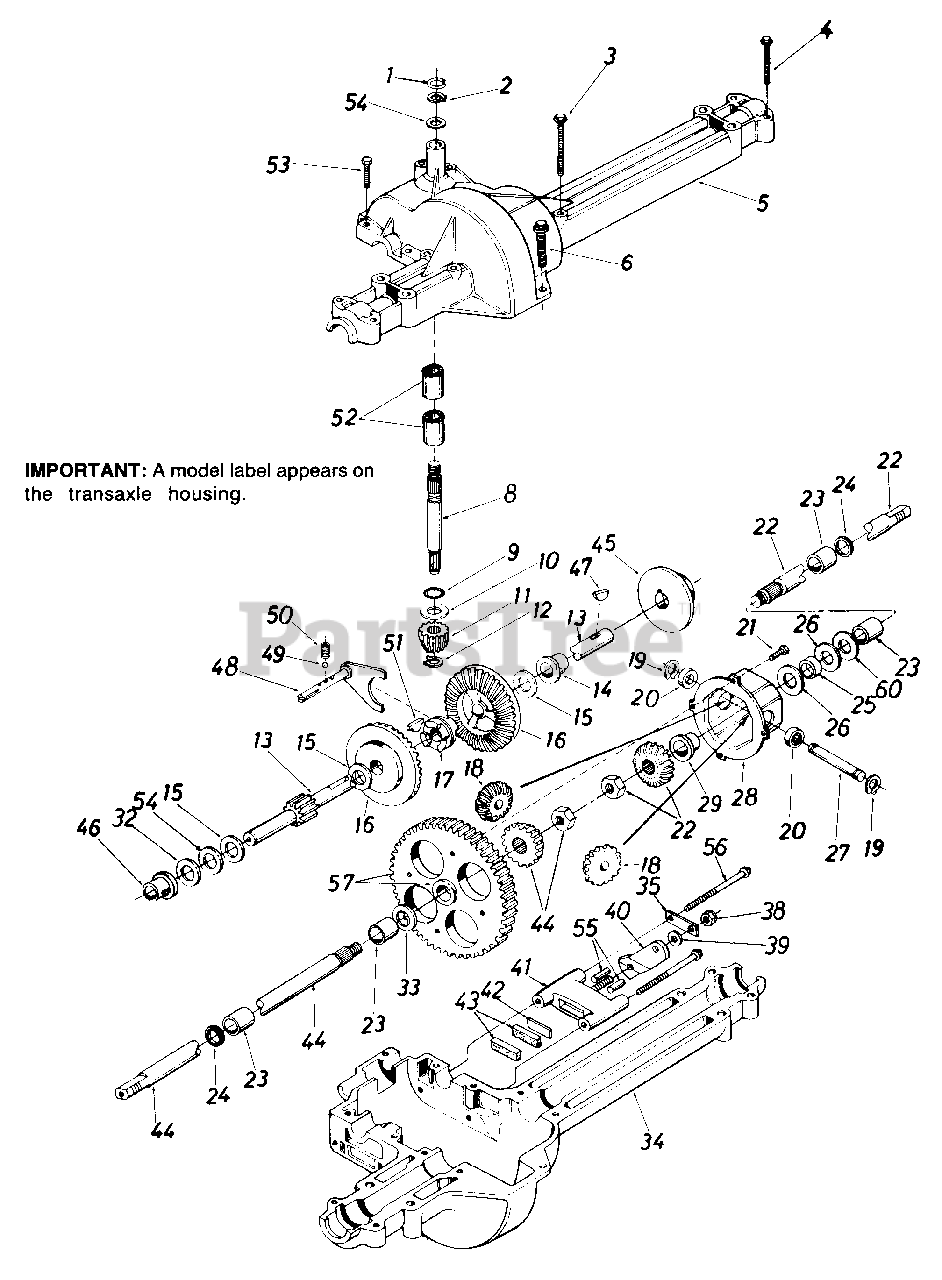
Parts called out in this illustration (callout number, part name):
1	Wire Ring
2	Retaining Ring
3	Hex Bolt 1/4-20 x 1.75" Lg.
4	Hex Tap Scr. 1/4-20 x 1.25" Lg.
5	Upper Housing
6	Hex TT-Tap Scr. 1/4-20 x .75" Lg.
8	Input Shaft
9	Square Seal 5/8" I.D.
10	Thrust Washer 5/8" I.D. x 1 25" O.D.
11	Pinion Input 14T
12	Retaining Ring
13	Drive Shaft
14	Flange Brg. 5/8" I.D. x 3/4" Lg.
15	Fl-Wash. 5/8" I.D. x 1.25
16	Bevel Gear 42T
17	Clutch Collar
18	Miter Gear 15T (H.D.)
19	Snap Ring
20	Thrust Bearing
21	Pan Head Scr. 1/4-20 x .50" Lg. w/Patch
22	Axle R.H. Ass'y.
23	Sleeve Bearing 3/4" I.D. x 1.0" Lg.
24	Oil Seal 3/4" I.D.
25	Axle Spacer
26	Fl-Wash. .760" I.D. x 1.5" O.D.
27	Cross Shaft
28	Differential Cam Ass'y.
32	Washer
33	Fl-Wash. .760" I.D. x 1.5" O.D.
34	Lower Housing
35	Anti-Rotation Brkt.
38	Hex Nut 5/16-24 Thd.
39	Fl-Wash. .344" I.D. x .875" O.D.
40	Actuating Arm
41	Brake Yoke
42	Puck Plate
43	Brake Puck
44	Axle L.H. Ass'y.
45	Brake Disc
46	Flange Bearing 5/8" I.D. x 15/16" Lg.
47	Woodruff Key 3/16 x 5/8 HT
48	Shift Fork Ass'y.
49	Ball Detent .250" Dia.
50	Spring Detent
51	#9 Hi-Pro Key 3/16" x 3/4" Dia. HT
52	Needle Brg. 5/8" I.D. x 1/2" Lg.
53	Hex Bolt 1/4-20 x 1.00" Lg.
54	Fl-Wash. 5/8" I.D. x 1" O.D. x .020 Thk.
55	Actuating Pin 5/16" Dia.
56	Hex Wash Hd. Self-Tap Scr. 1/4-20 Thd.
57	Differential Gear 72T Ass'y. w/Bearing
60	Washer
